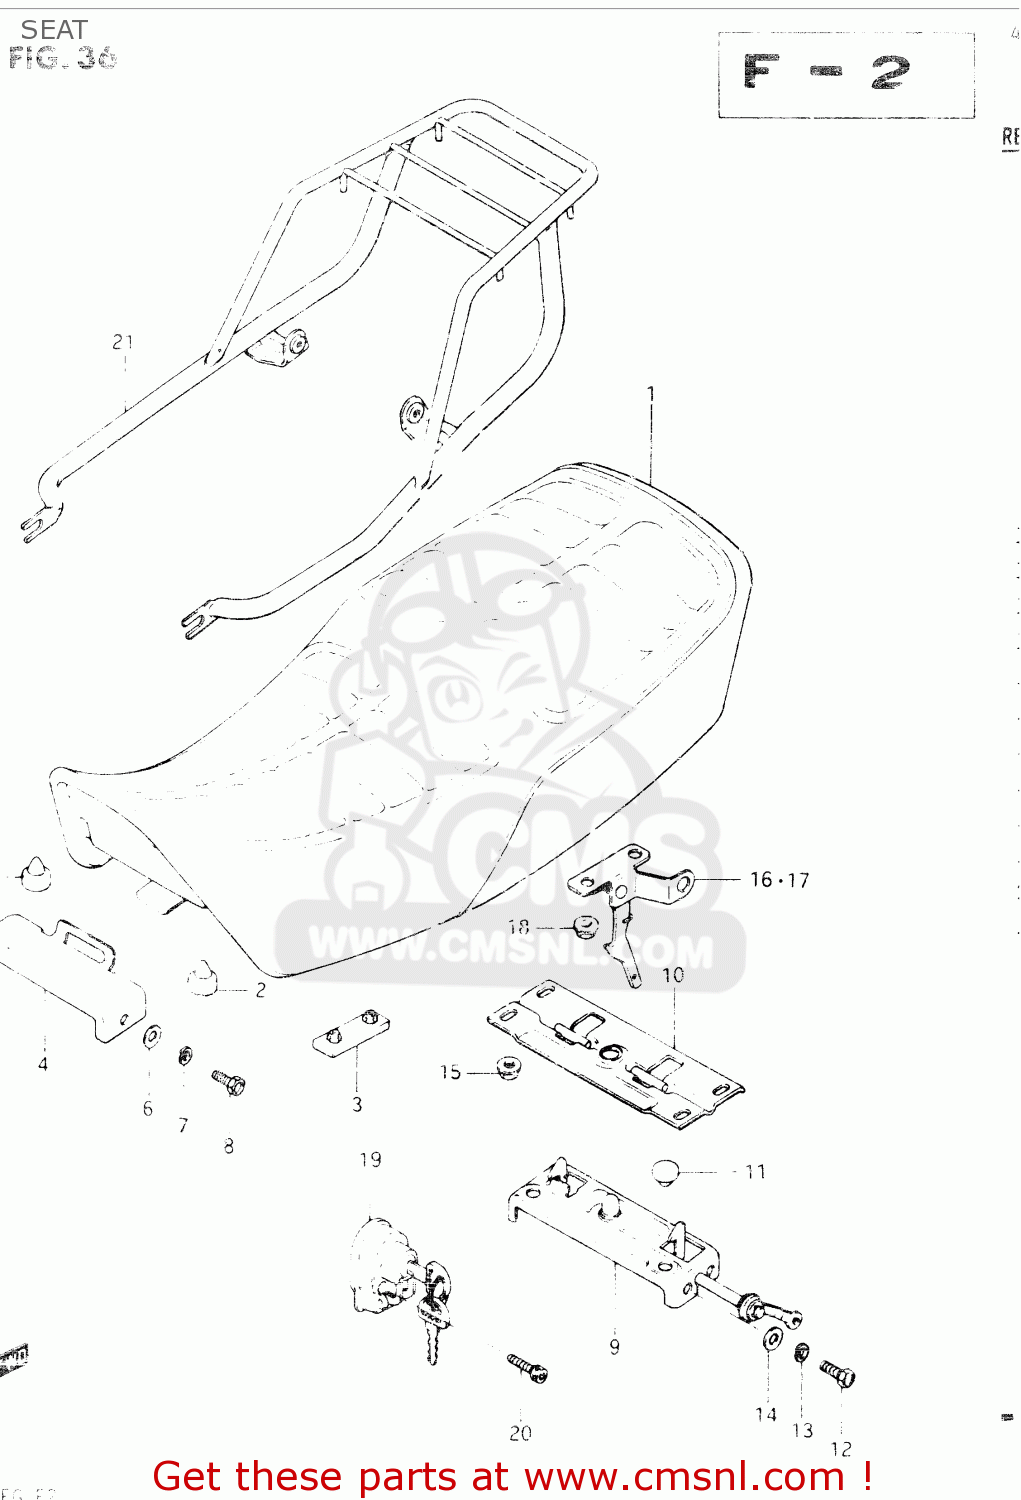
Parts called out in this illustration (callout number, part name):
1	SEAT ASSEMBLY
2	CUSHION
3	CUSHION
4	PLATE,SEAT LOCK,FRONT
5	CUSHION(11.5X22X20)
6	WASHER, LOWER
7	WASHER,LOCK
8	BOLT
9	PLATE,CLAMP GUIDE
10	PLATE,SEAT CLAMP GUIDE
11	CUSHION
12	SCREW 5X10
13	LOCK WASHER
14	WASHER
15	NUT
16	LEVER,SEAT HOOK,RIGHT
17	LEVER,SEAT HOOK,LEFT
18	NUT
19	LOCK ASSY,HELMET
20	BOLT
21	CARRIER
